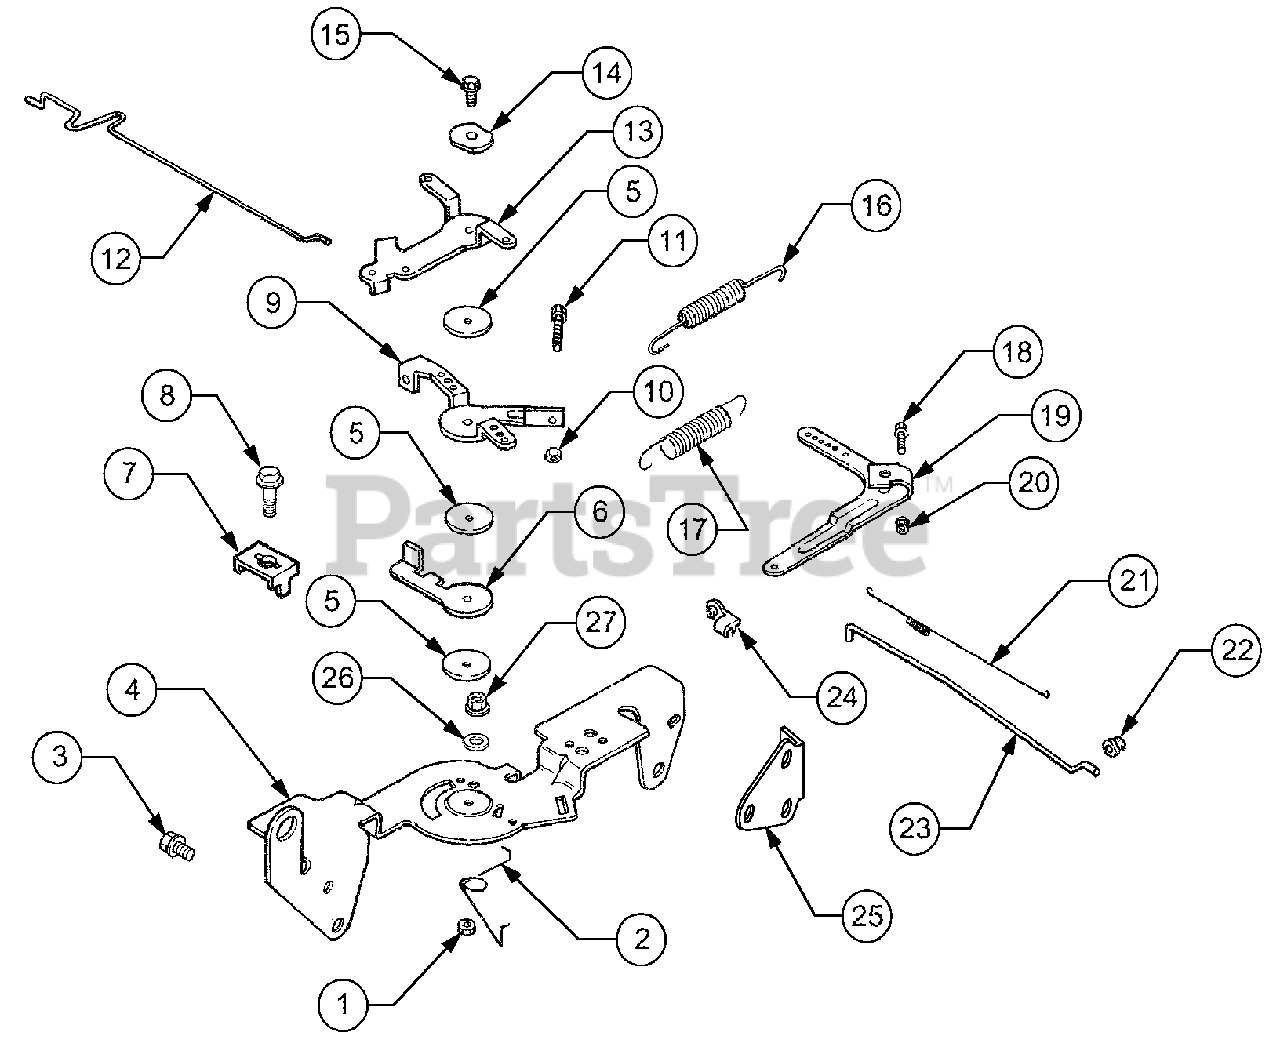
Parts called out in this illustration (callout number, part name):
1	Nut, Hex Lock M5 x 0.8
2	Spring, Choke Return
3	Screw, Hex Flange M6 x 1.0 x 16
4	Bracket, Control
5	Washer , Plain 5.5mm
6	Lever, Throttle Actuator
7	Clamp, Cable
8	Screw, Hex Flange M5 x 0.8 x 16
9	Lever, Throttle Control
10	Nut, Hex M4 x 0.7
11	Screw, Hex Cap M4 x 0.7 x30
12	Linkage, Choke
13	Lever, Choke
14	Washer, Spring 1/4"
15	Screw, Hex Flange M5 x 0,.8 x 20
16	Spring, Throttle Limiter
17	Spring, Governor
18	Screw, Round Hd. Square Neck
19	Lever, Governor
20	Nut, Hex Flange M6 x 1.0
21	Spring, Linkage
22	Bushing, Linkage Retaining
23	Linkage, Throttle
24	Bushing, Linkage Retaining
25	Bracket, Support
